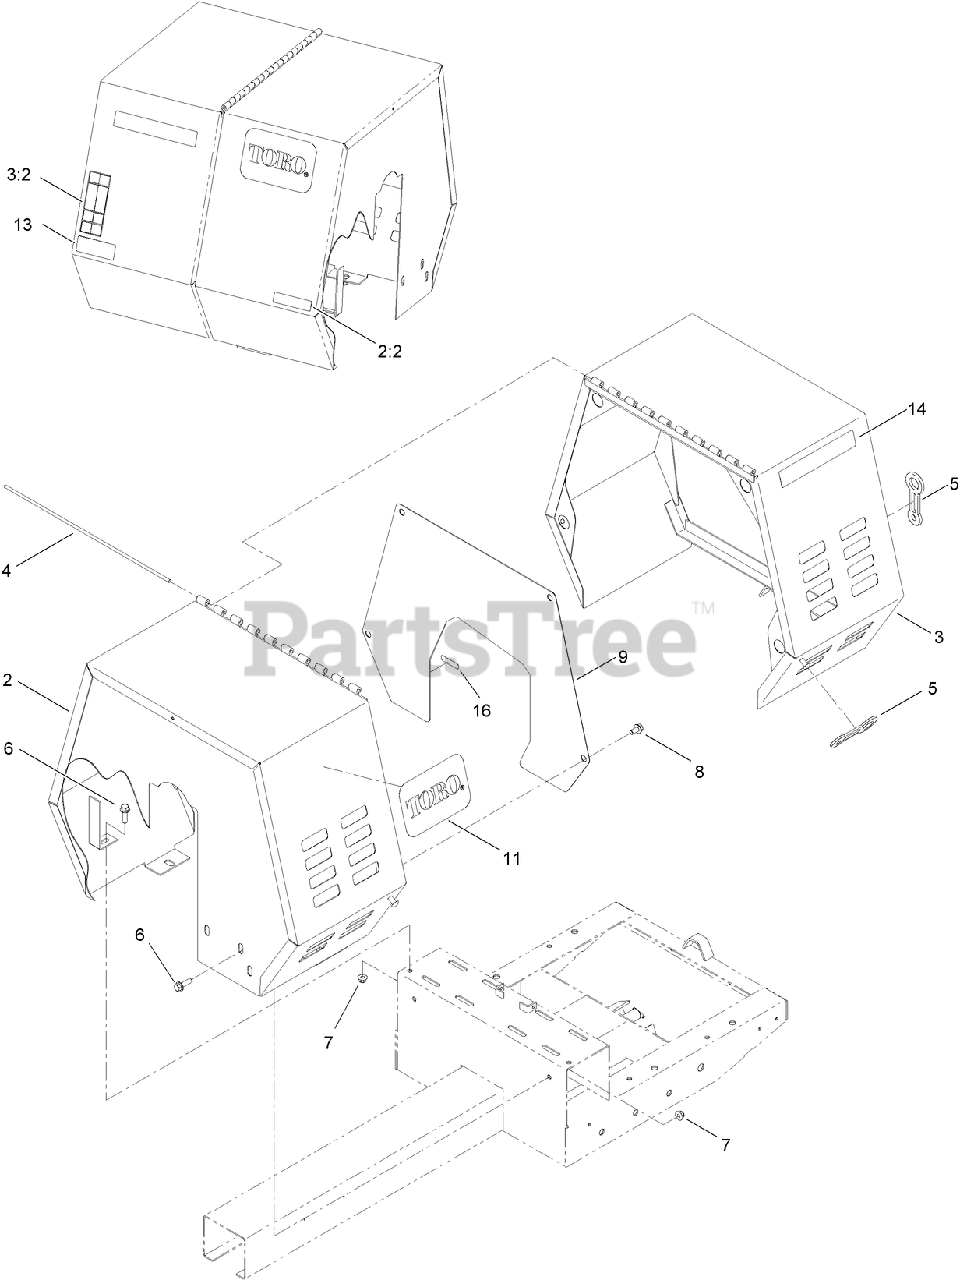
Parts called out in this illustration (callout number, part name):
2	STATIONARY COWL ASM
2:2	DECAL-ARRESTER, SPARK
3	MOVABLE COWL ASM
3:2	DECAL-WARNING
5	LATCH-RUBBER
6	SCREW-HHF
7	NUT-HF, NI
8	SCREW-HWH
9	PLATE-GUARD, BELT
11	DECAL
14	DECAL-MM-850E
16	DECAL-GREASE
